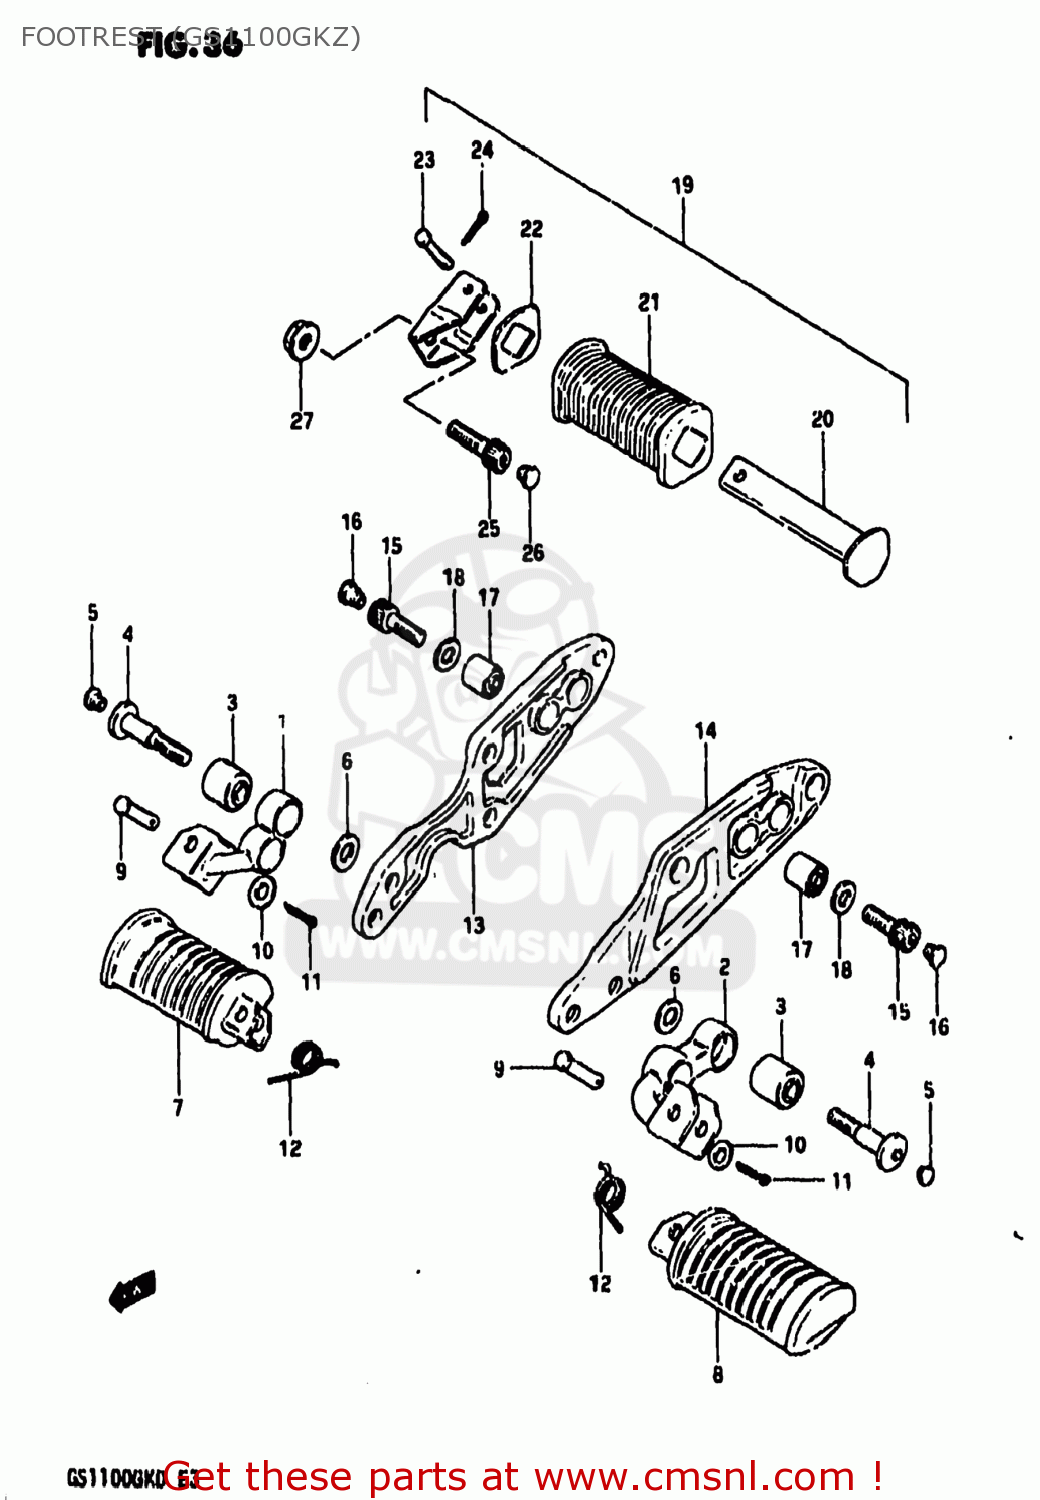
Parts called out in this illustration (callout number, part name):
1	BAR,FRONT FOOTREST,RIGHT
2	BAR,FRONT FOOTREST,LEFT
3	BUSH
4	BOLT(10X50)
5	CAP
6	WASHER
7	RUBBER,FRONT FOOTREST
8	FOOTREST
9	PIN
10	WASHER
11	PIN 20X20
12	SPRING
13	BRACKET,MUFFLER,RIGHT
14	BRACKET,MUFFLER,LEFT
15	BOLT
16	CAP
17	BUSH
18	WASHER
19	FOOTREST ASSEMBLY,REAR
20	BAR,REAR FOOTREST
21	RUBBER,REAR FOOTREST
22	WASHER,REAR FOOTREST RUBBER
23	PIN
24	PIN 20X20
25	BOLT
26	CAP
27	NUT
